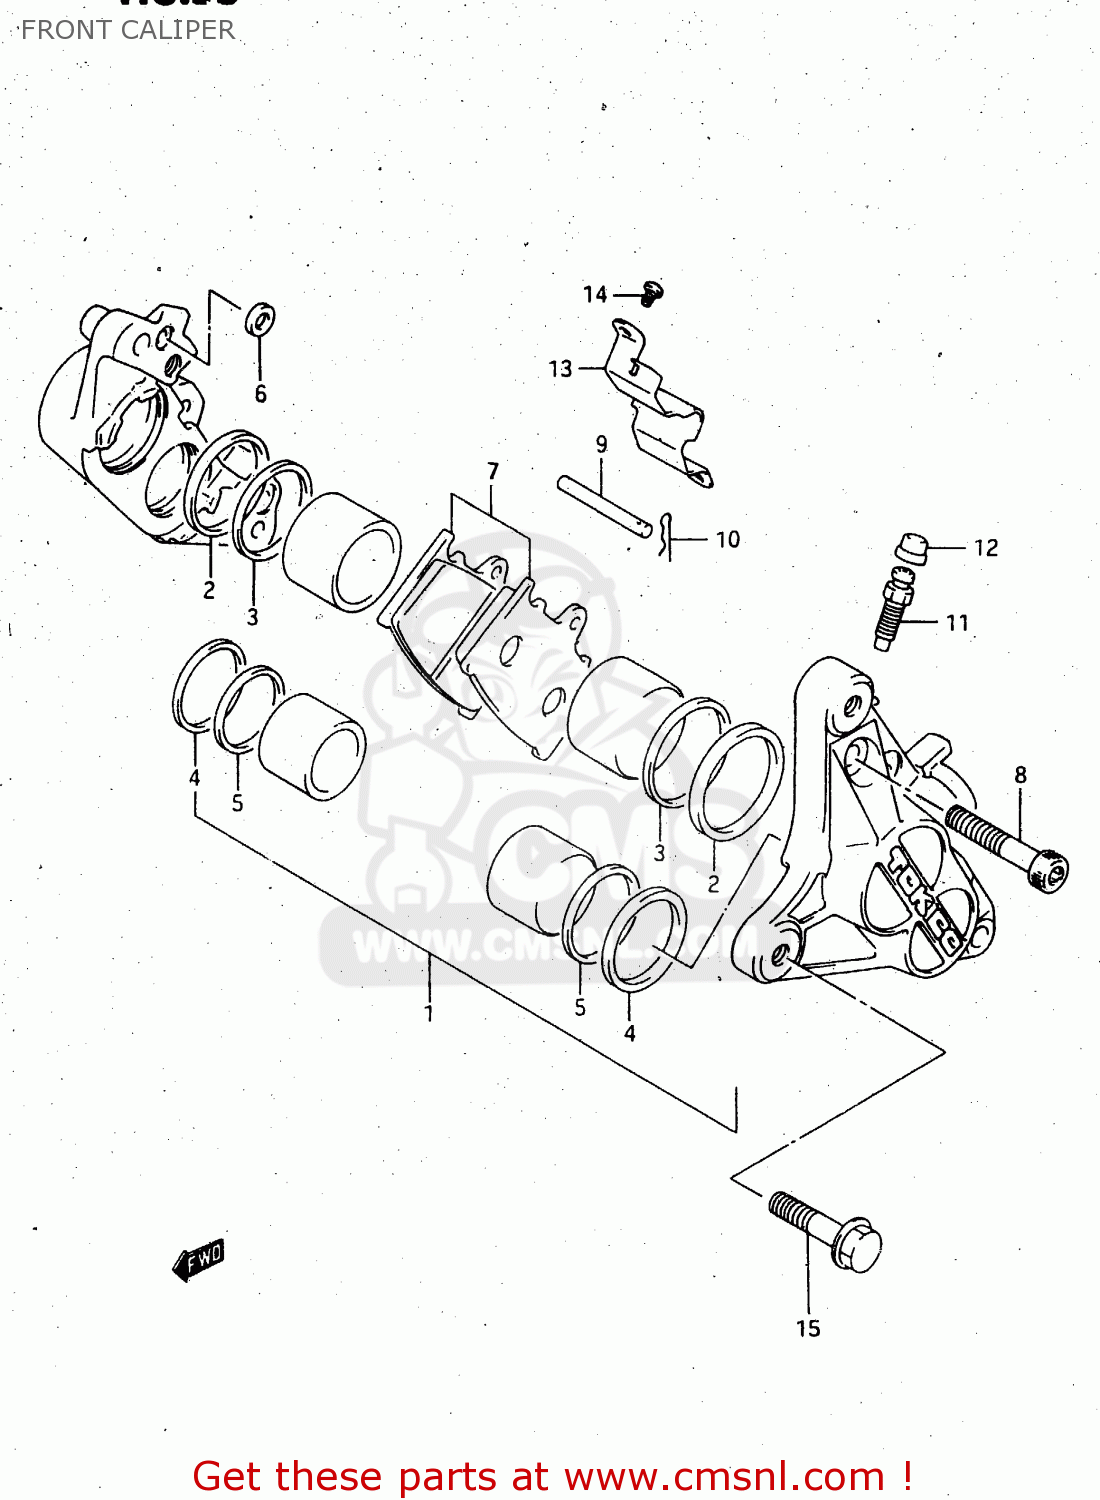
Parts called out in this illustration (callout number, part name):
1	PISTON SET,BRK
2	SEAL,PISTON
3	SEAL,WIPER
4	SEAL
5	SEAL,WIPER
6	SEAL,JOINT
7	PAD SET
8	BOLT,CALIPER
9	PIN,PAD
10	CLIP,PAD PIN
11	BLEEDER
12	CAP,BLEEDER PLUG
13	COVER,DUST,R.
14	SCREW
15	BOLT
